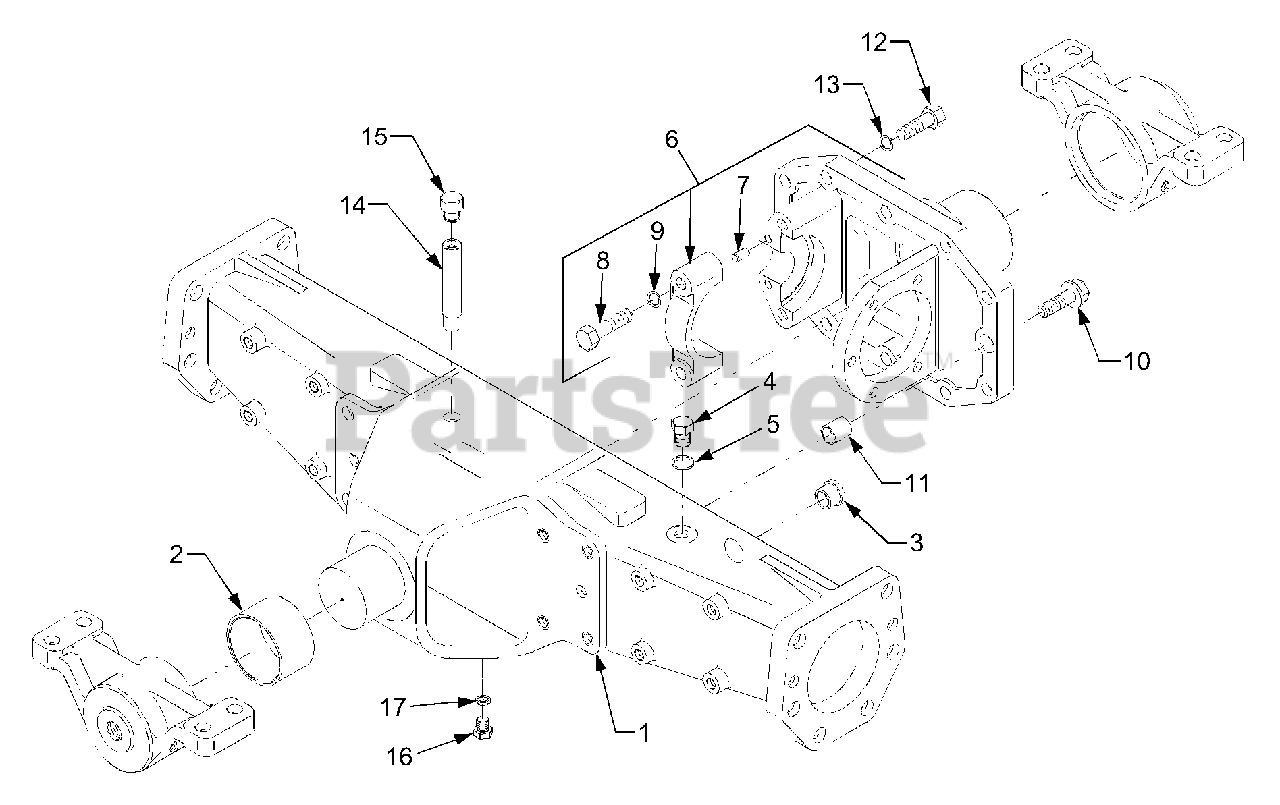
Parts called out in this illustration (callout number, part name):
1	Support, Front Axle
6	Diff. Gear Case Ass'y
7	Pin, Straight
9	Washer, Spring
13	Washer, Spring
